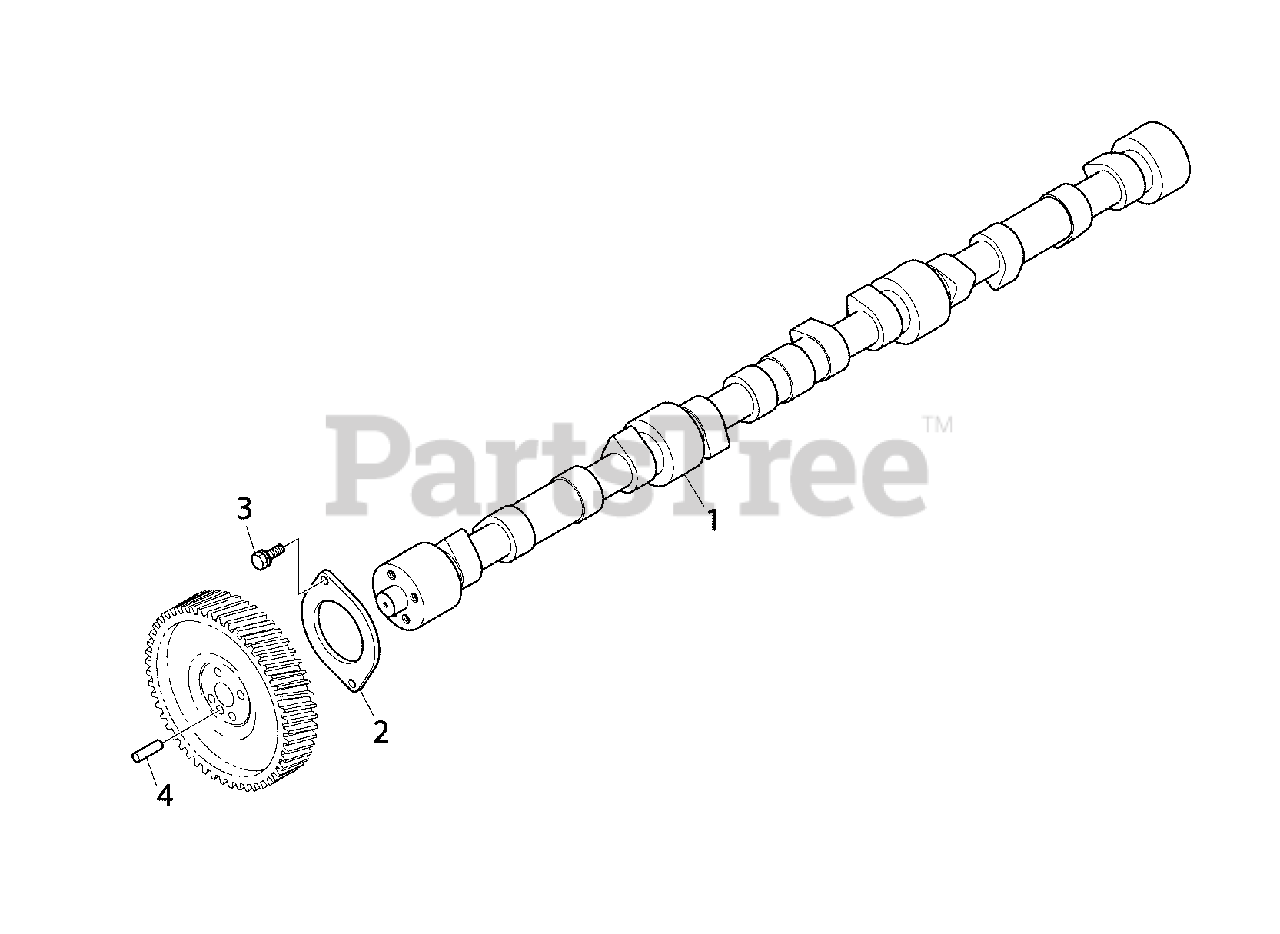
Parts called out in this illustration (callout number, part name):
1	* CAMSHAFT
2	* FLANGE
3	* BOLT
4	* PIN
